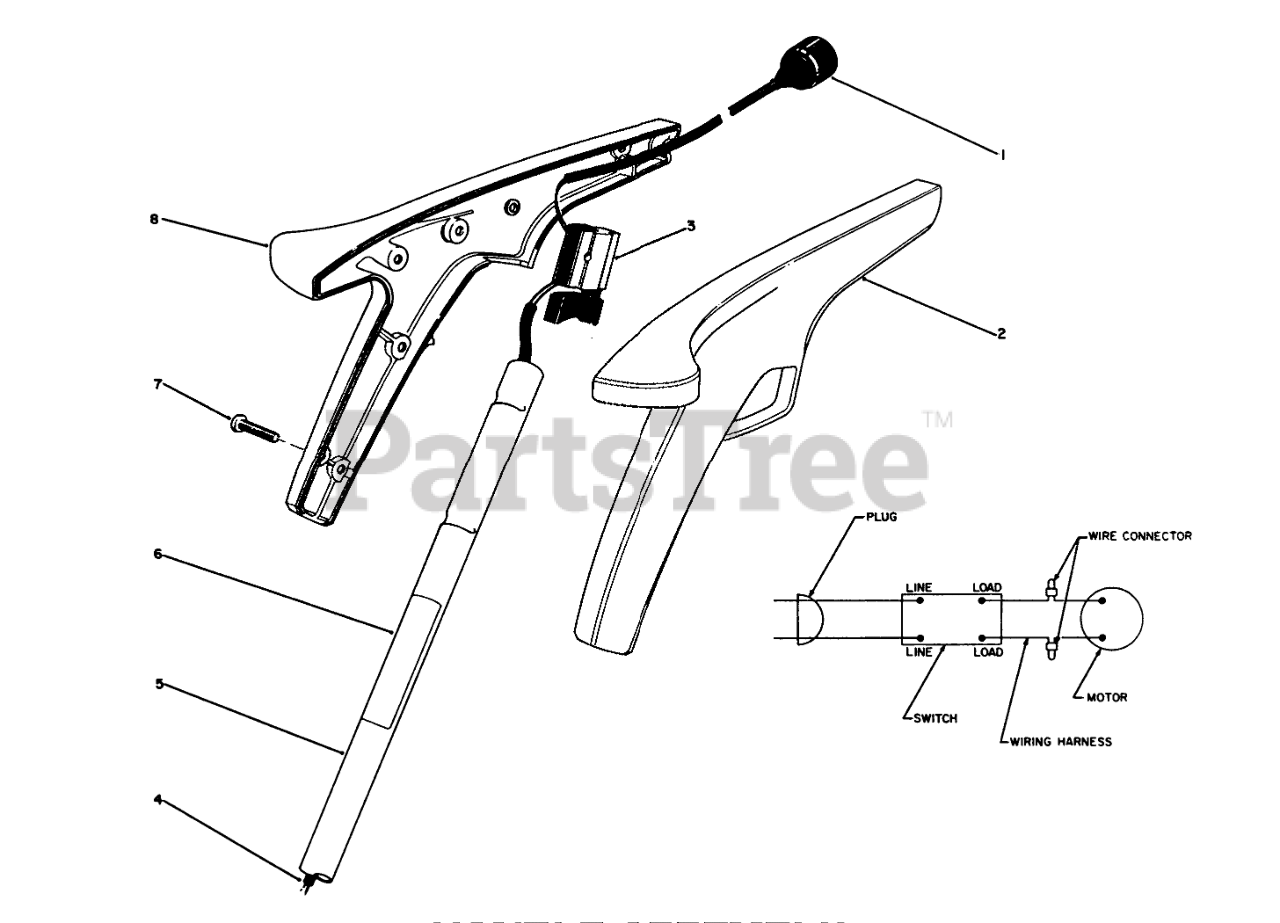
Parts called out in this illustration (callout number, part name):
1	SUPPLY CORD-CSA
2	LH HANDLE GRIP, 910
3	SWITCH SINGLE SPEED
4	WIRE HARNESS
5	TUBE EXTENSION
6	REP. SERIAL PLT
7	#8 X .625" PHILPS PAN H
8	Grip-R.H.
